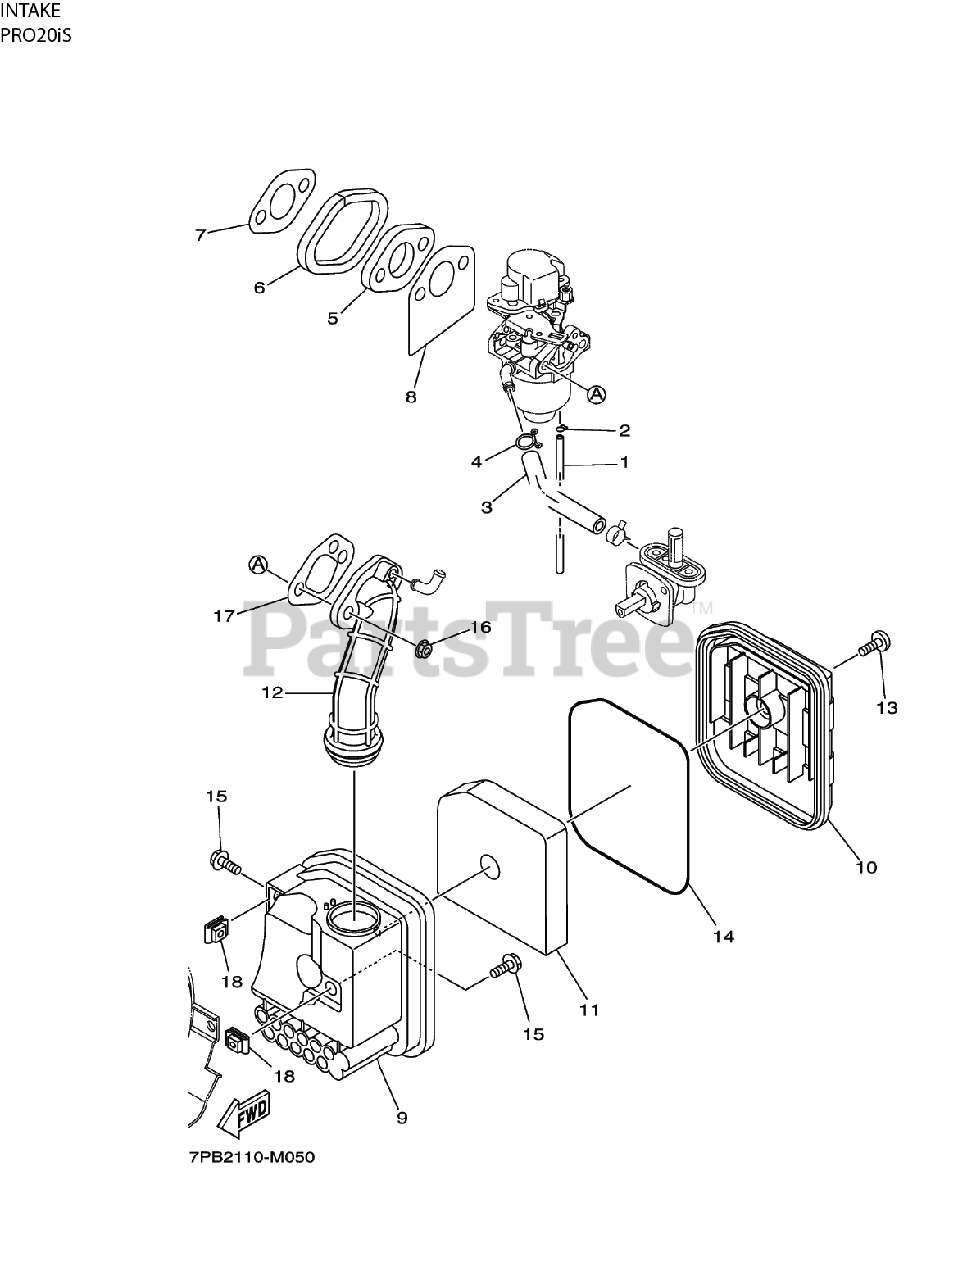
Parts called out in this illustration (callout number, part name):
2	HOSE - PIPE
3	FUEL HOSE, LOW PERMEATION
4	CLAMP - CLIP
5	INSULATOR - JOINT
7	GASKET, MANIFOLD
8	DEFLECTOR, GASKET
9	BASE, AIR CLEANER - CASE
10	COVER, AIR CLEANER - CAP CASE 1
11	ELEMENT, AIR CLEANER
12	MANIFOLD - JOINT AIR CLEANER 1
13	SCREW - BOLT
15	SCREW - BOLT
16	NUT, FLANGE
17	GASKET, AIR CLEANER
18	NUT, SPRING
